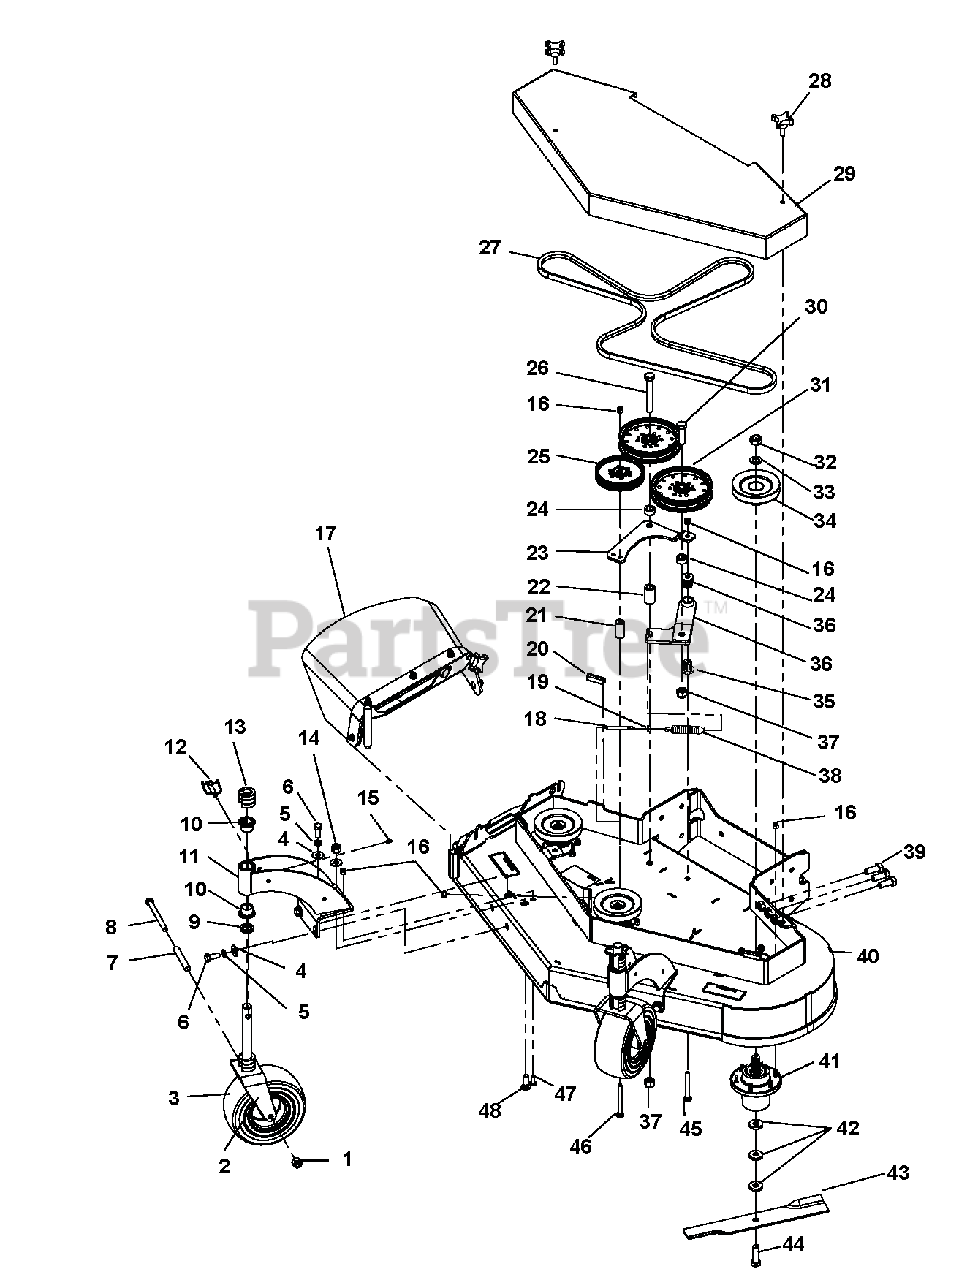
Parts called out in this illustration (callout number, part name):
1	LOCKNUT, 1/2-13 NYLOC Y
2	WLDT, CASTER YOKE GD BLACK
3	ASSY, WHEEL AND TIRE 9X3.5
4	MANUAL, OWNERS RAPID XZ FRENCH
5	WASHER, .500 MED SPRG LOCK Y
6	BLT-HEX .50-13X1.25 GR5 YWZC
7	TUBE, CASTER AXLE
8	BLT-HEX .50-13X5.50 GR5YWZC
9	BUSHING, 1.03 X 1.50 X .179 Y
10	BRG, FLG 1.00X1.25X1.00
11	WLDT, STRUT FRONT FXWLK SCAMPR
12	PIN, KLIK .438X2.00
13	C-SPACER, 1.00 X 1.77 X .500
14	LOCKNUT, 1/2-13 NYLOC Y
15	FTG, 1/4-28 STRGT GREASE ZERK
16	LOCKNUT, 3/8-16 NYLOC Y
17	ASSY, DISCHARGE SHIELD GD
18	ROD, THREADED ADJUSTMENT
19	LOCKNUT, 3/8-16 WHIZ Y
20	TRIM, LOCK 1/4" EDGE
22	BUSHING, .688X1.13X1.89
23	STRAP, IDLER 52 FXWLK G2
24	BUSHING, .688 X 1.13 X .55
25	PULLEY, FLAT IDLER
26	BLT-HEX .62-11X4.50 GR5 YWZC
27	BELT, HB 114.9 EL AMD
28	KNOB, 3/8 X 1.25 - 4 PRONG
29	WLDT, BELT SHIELD 48 FXWLK GD
30	BLT-HEX .62-11X2.25 GR5 YWZC
31	PULLEY, FLAT 6.00X.635 W/BRG
32	LOCKNUT, 3/4-16 CROWN PL
33	WASHER, .75X1.3125X.120
34	PULLEY, SPLINE SPINDLE LSE
35	BRG, FLG M10XM25XM27 FLUTED
36	WLDT, IDLER ARM 52 FXWLK G2
37	NUT-LK-NYL .625-11 YWZC
38	SPRG, EXTENSION
39	BOLT, HEX 5/8-11 1.5" GR8 YWZC
40	ASSY, DECK 48" SCAMPER W/DECAL
41	ASSY, SPINDLE S/O
42	WASHER, .630X1.50X.250 FLAT Y
43	BLADE, 16.500 X .80 LIFT
44	BOLT, 5/8-11 X 2.00 HEX 8 Y
45	BOLT, 3/8-16X3.50 CRG 5 Y
46	BOLT, 3/8X4 SHTNK RDHD BOLT A1
47	BOLT, 3/8-16X1.00 CRG 5 SN Y
48	BLT-RDHDSQNK .50-13X1.50 G5YZ
